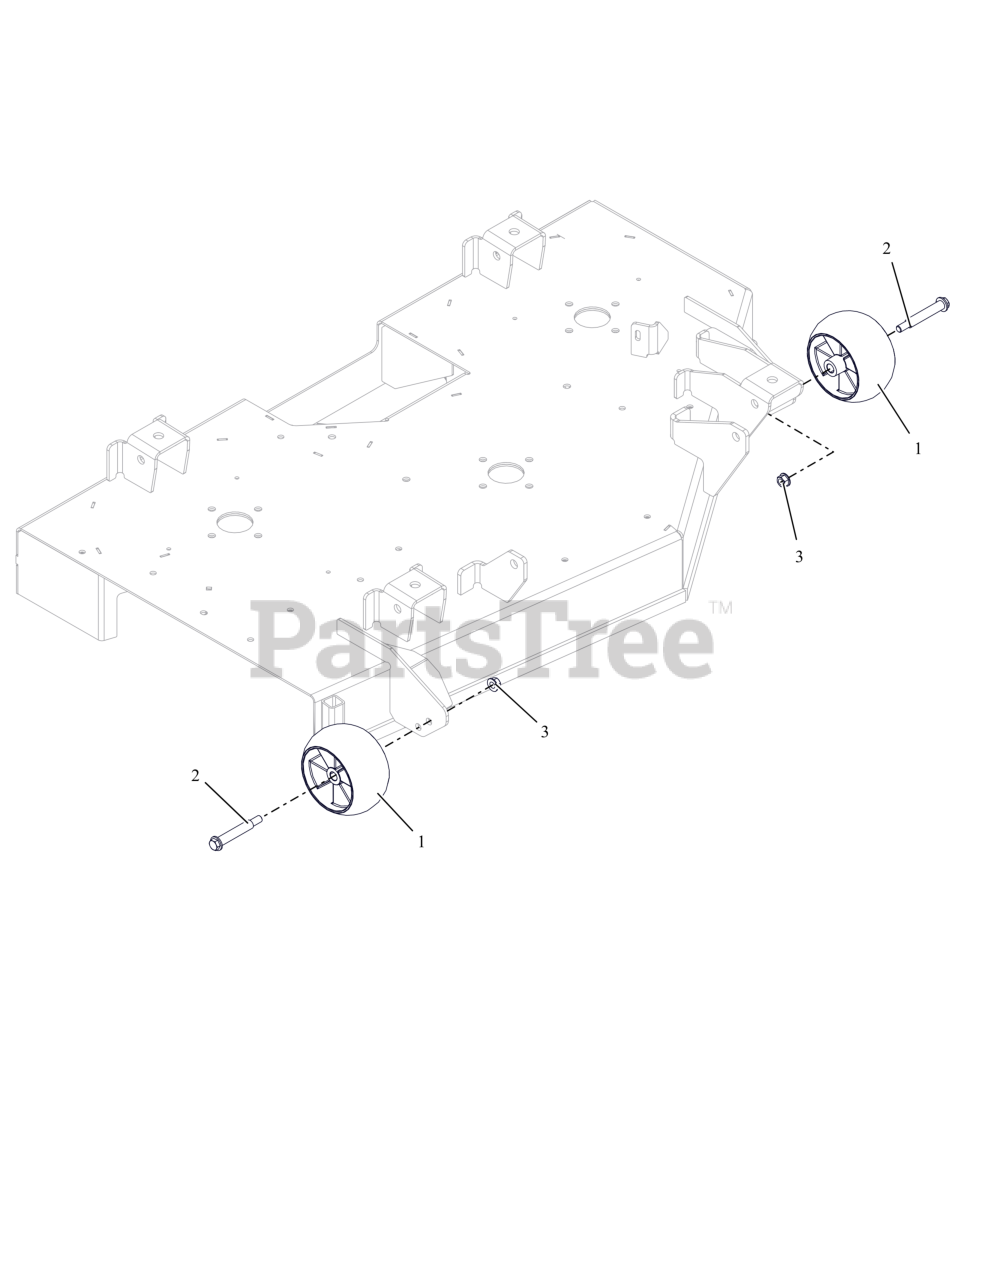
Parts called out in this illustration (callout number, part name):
1	ANTI-SCALP WHEEL - 5X OS
2	BLT-SHLDR .38-16X2.50 HWH G5
3	NUT-LK-CTR-FLG .375-16 GF ZCC
